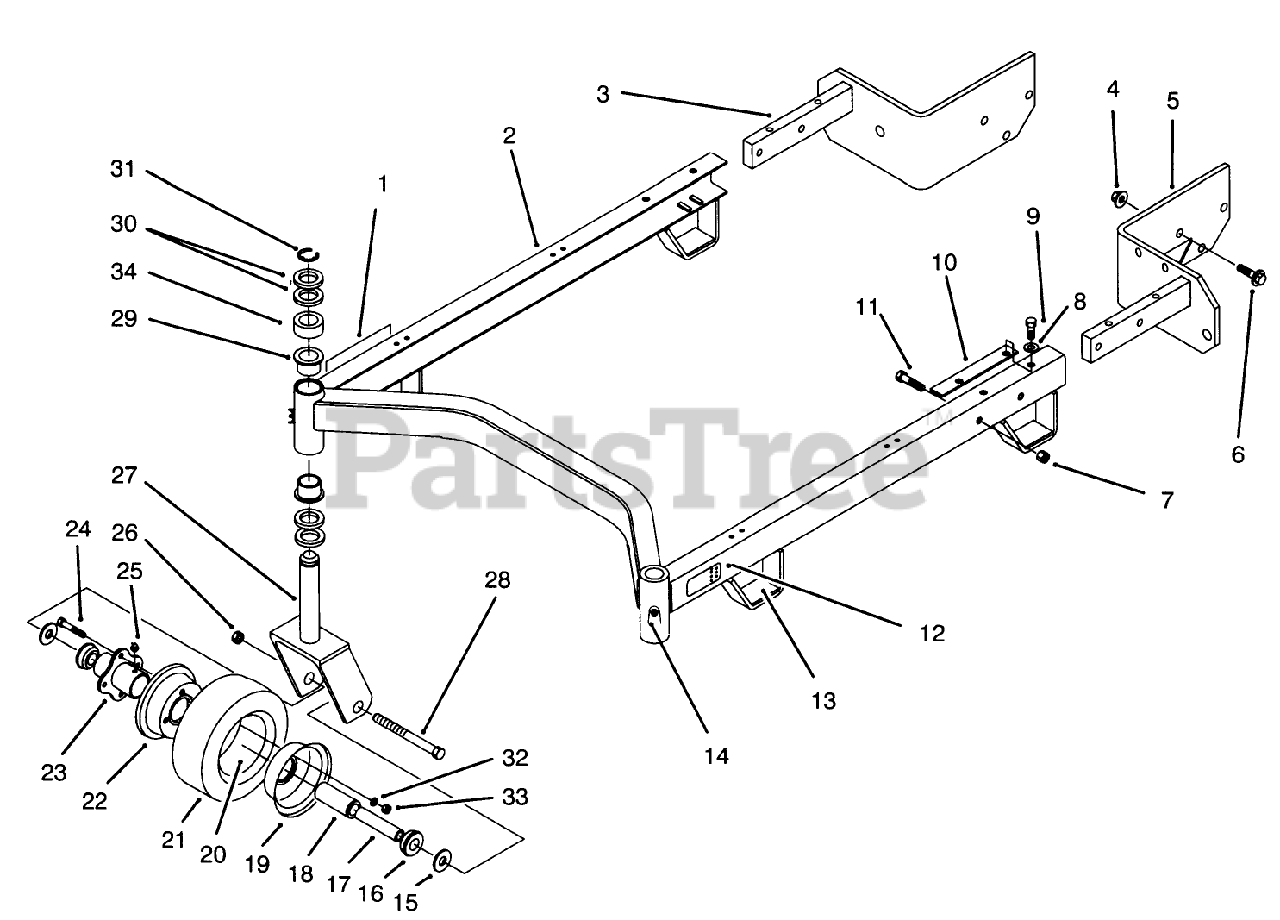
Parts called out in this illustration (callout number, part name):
1	DECAL-HOC, RH
2	WA - SUSPENSION
3	Bracket RH
4	NUT-HF
5	Bracket-LH
6	SCREW-HHF
7	NUT-LOCK, CONE
8	WASHER-FLAT
9	SCREW W/PATCH
10	SHIM-CARRIER
11	SCREW-HH
12	DECAL-HOC, LH
13	CUSHION-RUBBER
14	FITTING-GREASE
15	WASHER-FLAT
16	BEARING-OUTSIDE
17	SPANNER-TIRE
18	BEARING-ROLLER
19	MALE WHEEL HALF
20	TUBE-INNER (W/VALVE)
22	FEMALE WHEEL HALF
23	HUB-CENTER
24	WHEEL BOLT
25	FITTING-GREASE
26	NUT-HEX
27	Fork
28	SCREW-HH
29	BUSHING
30	WASHER-THRUST
31	RING-RETAINING
32	WASHER-LOCK
33	NUT-HEX
34	SPACER-CASTOR
